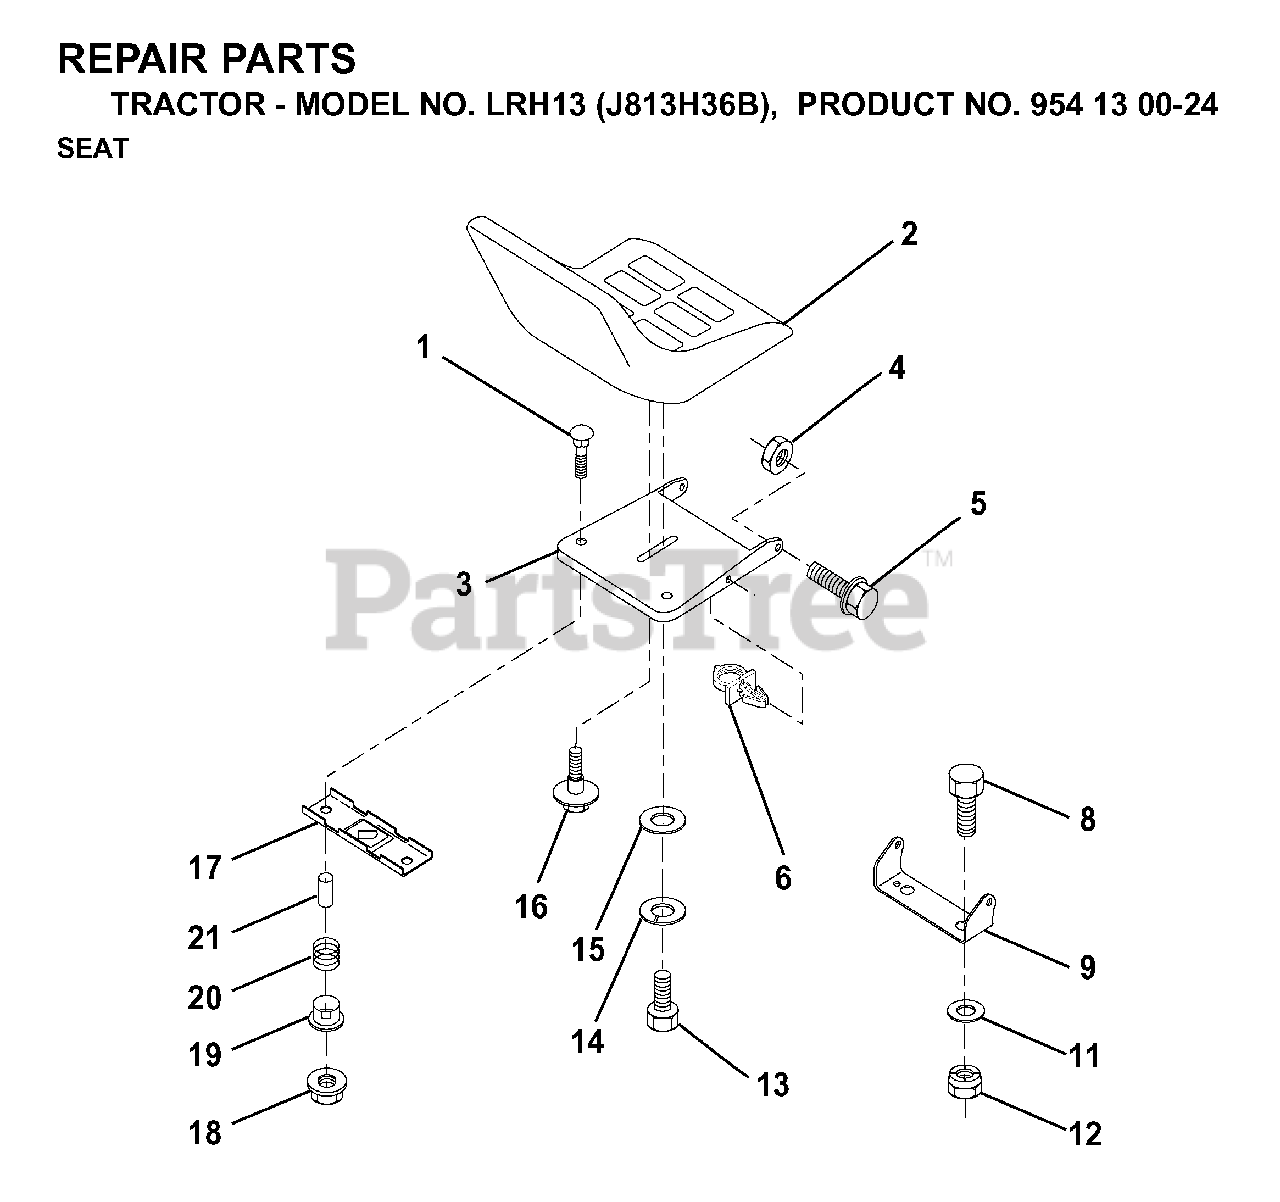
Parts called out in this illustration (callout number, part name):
1	BOLT.ROUND.HEAD.SQUARE.NECK
2	SEAT
3	PAN, SEAT
4	NUT.71038.31-18.HEX.NYLOCK
5	BOLT SHOULDER 5/16-18
6	PUSH CLIP
8	BOLT
9	SEAT PIVOT BRKT
10	CLIP,INSULATOR
11	WASHER 12/32X2X10GA
12	NUT
13	BOLT
14	LOCKWASHER
16	BOLT,SHOULD
17	BRKT SWITCH
18	NUT T
21	SPACER SPLIT 28X.96
